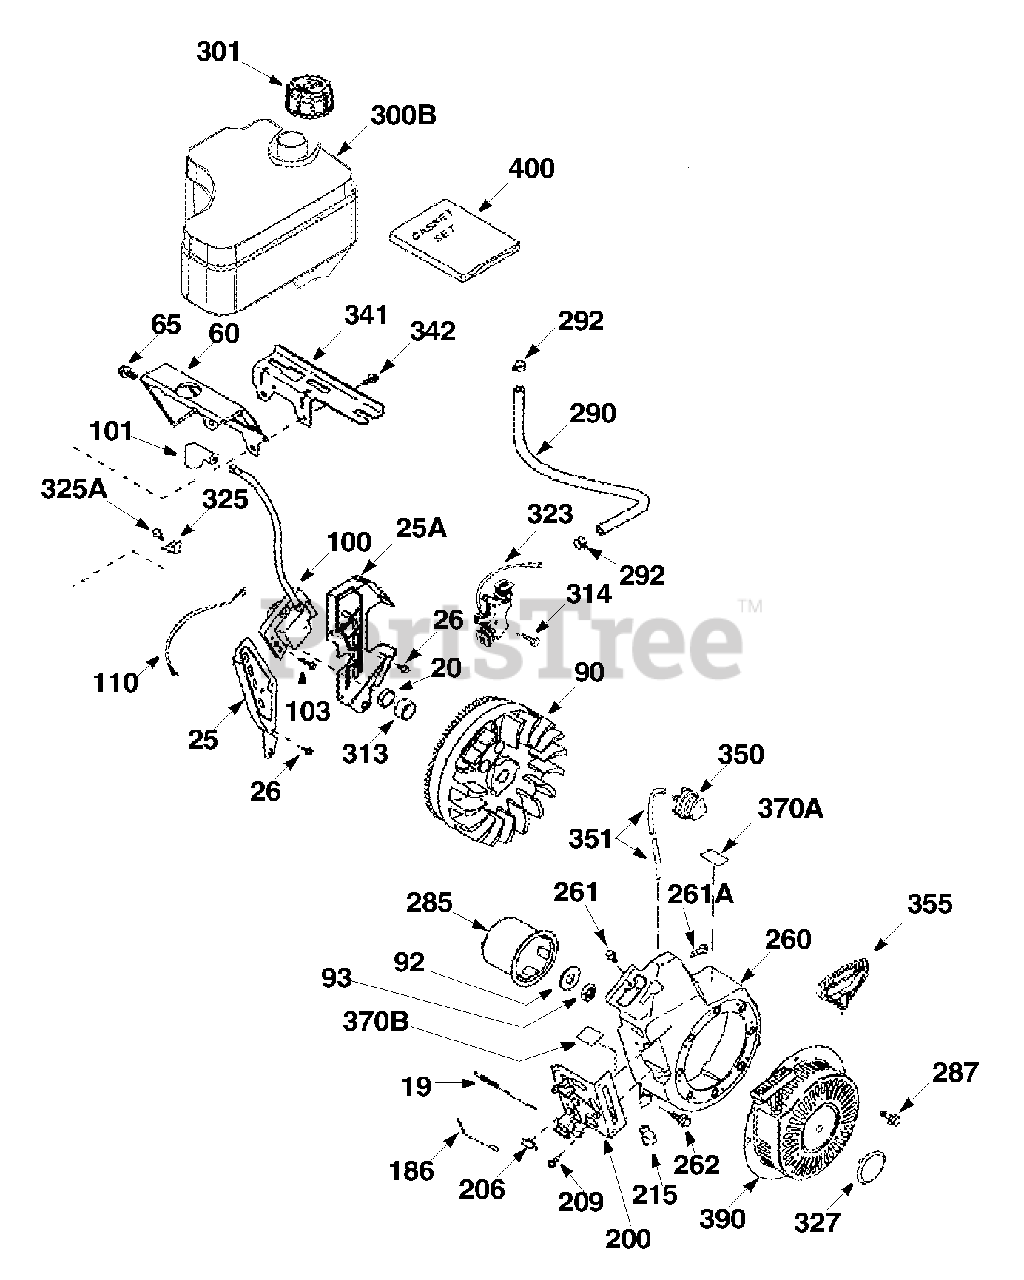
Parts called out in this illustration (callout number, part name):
19	Extension Spring
20	Oil Seal
25	Air Baffle (Left)
25A	Air Baffle (Right)
26	Screw, 10-24 x 9/16"
60	Blower Housing Extension
65	Screw, 10-24 x 9/16"
90	Flywheel
92	Belleville Washer
93	Flywheel Nut
100	Solid State Ignition
101	Spark Plug Cover
103	Screw, T-15, 10-24 x 15/16"
110	Ground Wire
186	Governor Link
200	Control Bracket
206	Terminal
209	Screw, 10-32 x 1/2"
215	Control Knob
260	Blower Housing
261	Screw, 1/4-20 x 31/64"
261A	Screw, 10-32 x 1/2"
262	Screw, 1/4-20 x 31/64"
285	Starter Cup
287	Screw, 1/4-20 x 31/64"
290	Fuel Line
292	Fuel Line Clamp
300B	Fuel Tank
301	Fuel Cap
314	Screw, 1/4-20 x 3/4"
325	Fuel Line Bracket
325A	Screw, 10-24 x 9/16"
327	Starter Plug
341	Fuel Tank Bracket (Lower)
342	Screw, 1/4-20 x 7/8"
350	Primer Assembly
351	Primer Line
355	Starter Handle (Mitten Grip)
370A	Lubrication Decal
370B	Control Decal
390	Rewind Starter
400	Gasket Set
